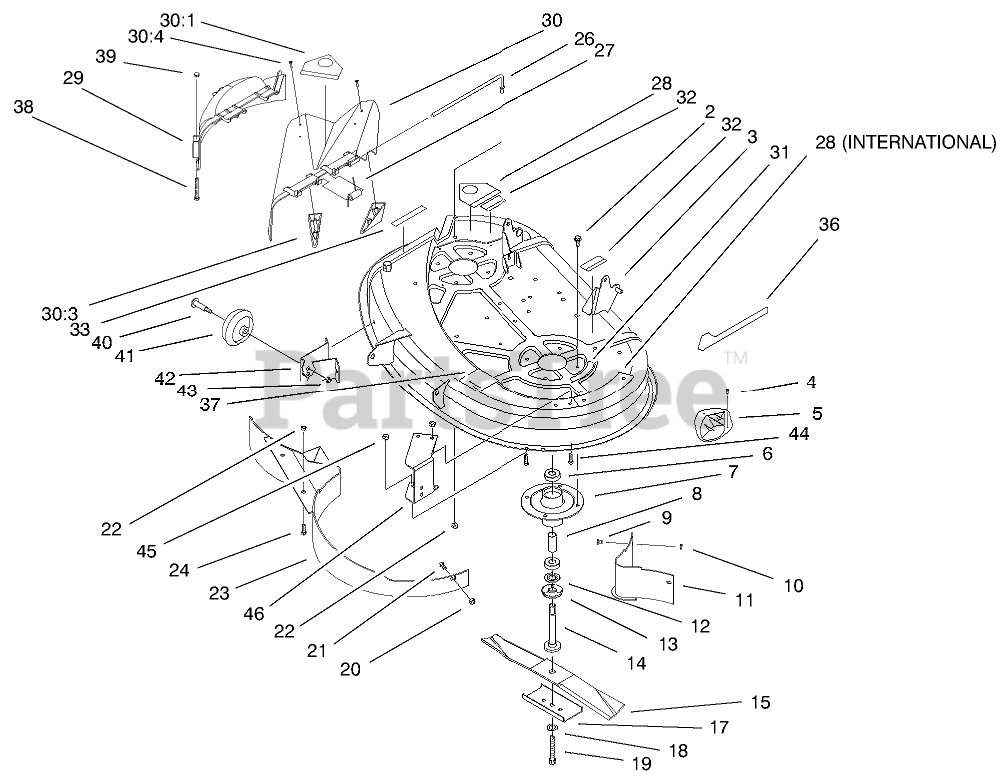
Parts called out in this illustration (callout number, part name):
2	SCREW-TAPTITE
3	DECK ASM
4	SCREW-PPH
5	PLATE-KICKER
6	BEARING-BALL
7	HOUSING-SPINDLE
8	SPACER
9	SCREW-HH
10	NUT-LOCK, NI
11	BAFFLE ASM
12	SPACER
13	SHIELD-BEARING
14	SHAFT-SPINDLE
15	Blade
17	STIFFENER-BLADE
18	WASHER-BELLEVILLE
19	SCREW-HH
20	NUT-LOCK, NI
21	BOLT-CARR
22	NUT-LOCK, NI
23	BAFFLE ASM
24	SCREW-HH
26	ROD-PIVOT
27	SPRING
28	DECAL-DANGER
29	COVER-RECYCLER
30	DEFLECTOR ASM
30:1	DECAL-DANGER
30:3	KICKER
30:4	SCREW-PPH
31	DECAL-DANGER, SHIELD
32	DECAL-WARNING
33	DECAL-DANGER
36	DECAL-RECYCLER DECK 38"
37	DECAL-ROUTING, BELT
38	SCREW-HH
39	NUT-CAP
40	SCREW-SHOULDER, HWH
41	WHEEL-GAGE
42	BRACKET-WHEEL, RH
43	NUT-LOCK, NI
44	SCREW-HH
45	NUT-LOCK, NI
46	BRACKET-WHEEL, LH
